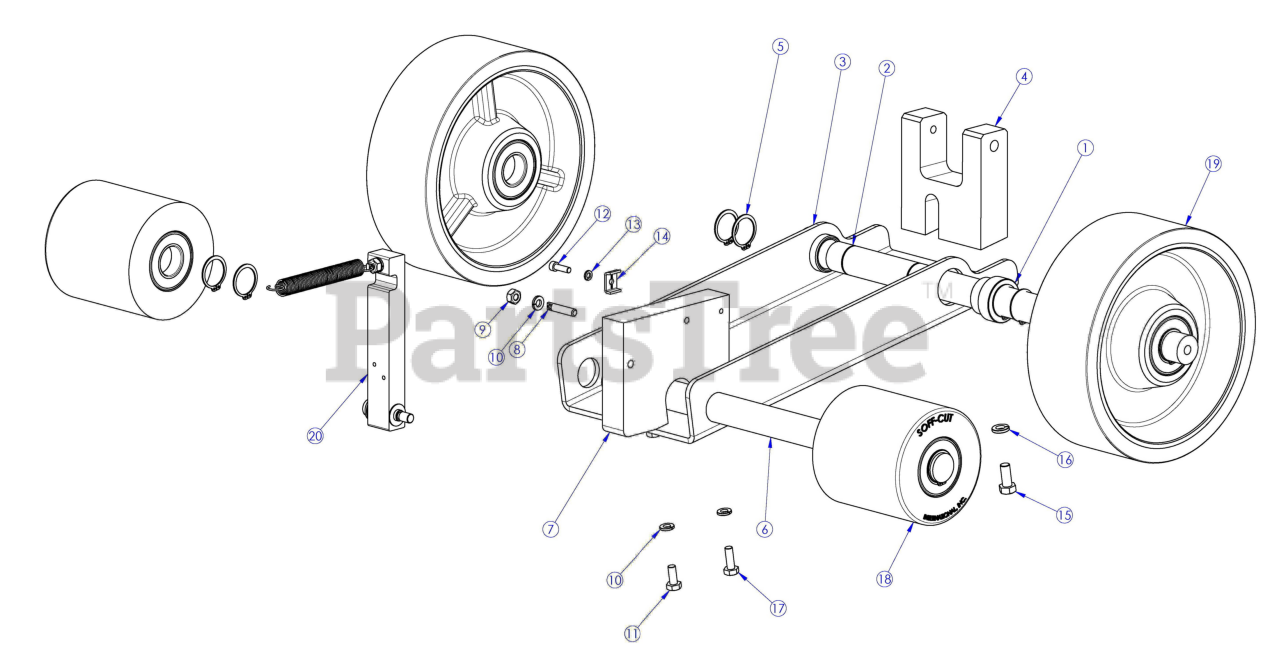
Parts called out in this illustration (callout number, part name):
1	Bushing, Axle, Delrin
2	Rear Axle, X750
3	Frame, Front Wheel
4	Block, Pump Support
5	Snap Ring, Ext 1.000"
6	Front Axle, X750
7	Bracket, Depth Stop
8	Spring Anchor, 1/4-20 X 1
9	Nut, 1/4-20 Hex, S.S.
10	Washer, Split 1/4" S.S.
11	HHB 1/4-20 X .625 S.S.
12	Shcs 10-32 X 5/8 S.S.
13	Washer, Split #10 S.S.
14	Clamp, Metal
15	HHB 5/16-18 X .75
16	Washer, Split 5/16" S.S.
17	HHB 1/4-20 X .75 S.S.
18	Wheel Assy, 4"D X 4"W, No Hub
19	Wheel Assy, Rear, 8" D X 2.81" W
20	Blade Release Arm
